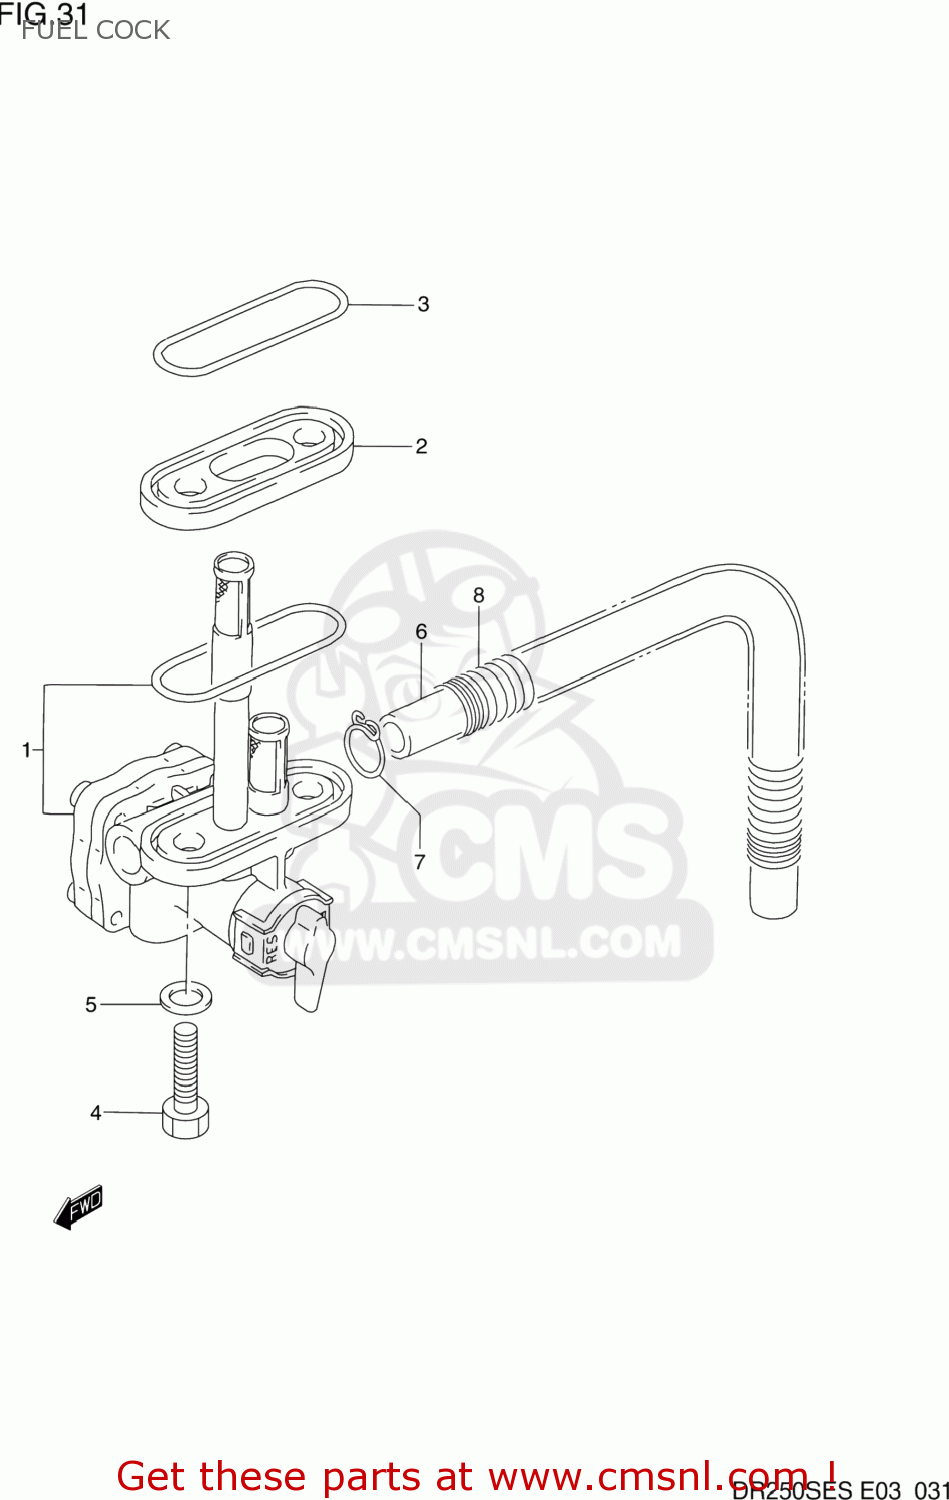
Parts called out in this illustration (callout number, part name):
1	COCK ASSY,FUEL
2	SPACER,FUEL COCK
3	GASKET,FUEL COCK (NAS)
4	BOLT(6X20)
5	GASKET(6.4X11.5X0.8) (NAS)
6	HOSE(7X10.2X600)
7	CLIP
8	SPRING
